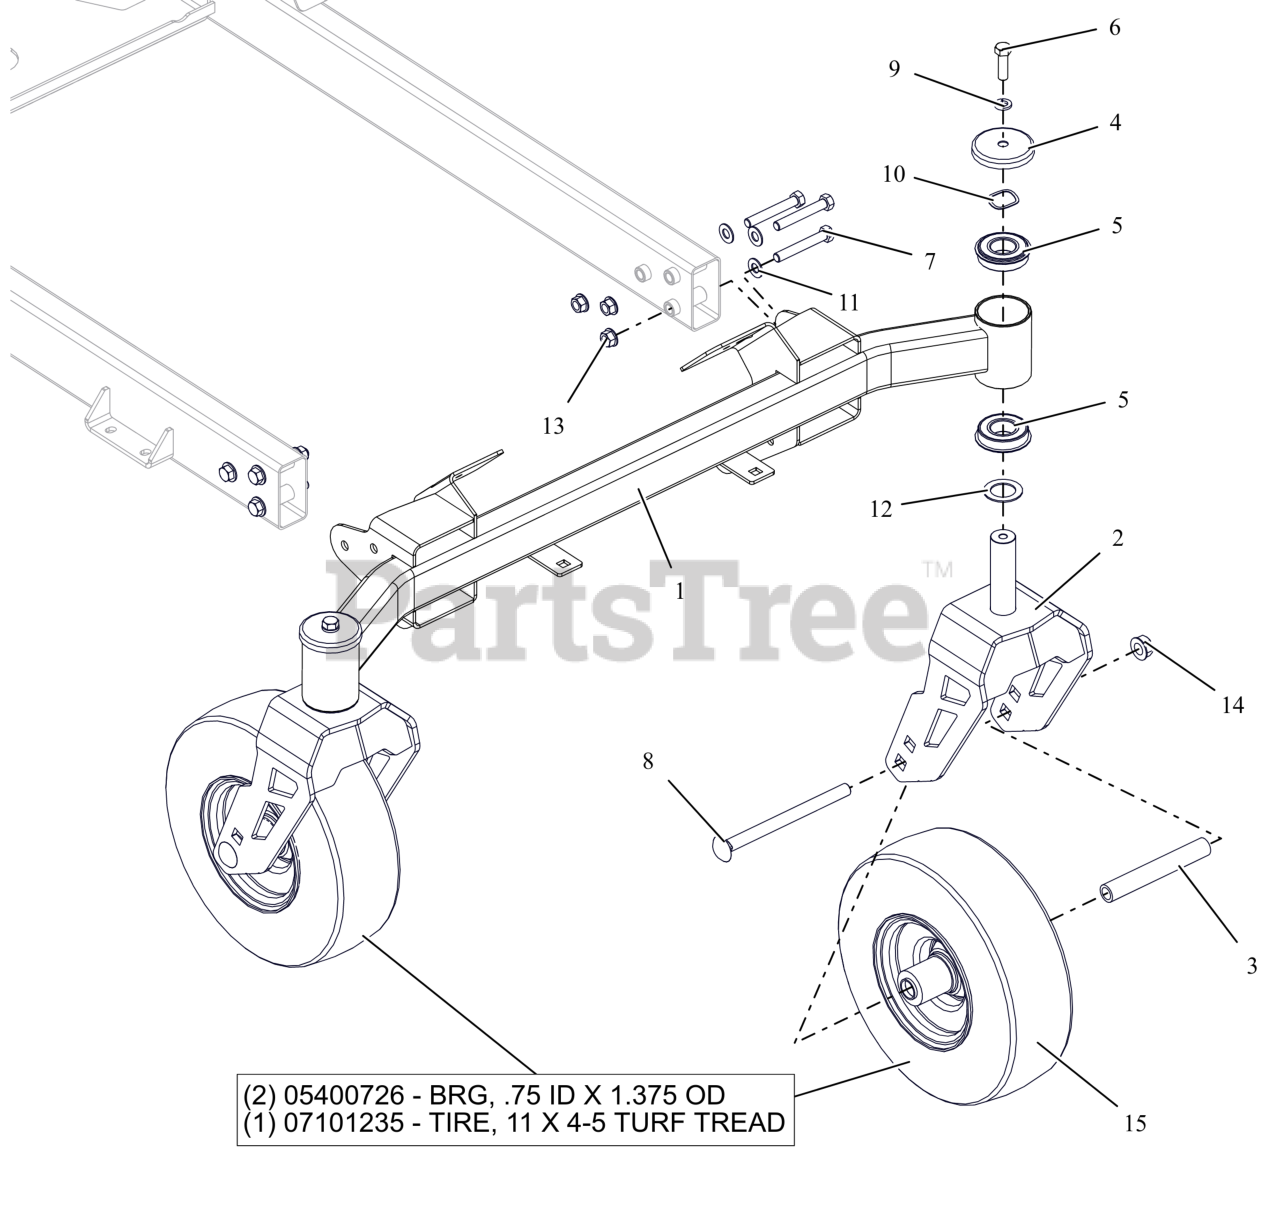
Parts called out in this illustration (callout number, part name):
1	WMT-FRONT AXLE-X/XL
2	WLDMT, CASTER FORK-XD (ORANGE)
3	SPACER, ROLLED WHEEL
4	SHIELD, AXLE BEARING
5	BEARING, BALL -2.000 OD X 1.000 ID X .5625 W/RING
6	BLT, HEX .38-16X1.25 G5 ZCC
7	BLT, HEX .38-16X2.50 G8 ZCC
8	BLT, RHSN .50-13X6.50 G5 ZCC
9	WSHR,LK-REG .375X.094 ZCC
10	WSHR-WAVE 1.0X1.25X.028 .145FH
11	WSHR,FLT-HRD.406X.812X.055 MZC
12	WSHR-HRD-THRS 1.007X1.542X.062
13	NUT-LK-TOP-FLG .375-16 GG ZCC
14	NUT-LK-TOP-FLG .500-13 GF ZCC
15	ASM, WHL/TIRE 11X4.00-5
15	BRG, .75 ID X 1.375 OD
15	TIRE, 11X4-5 TURF TREAD
